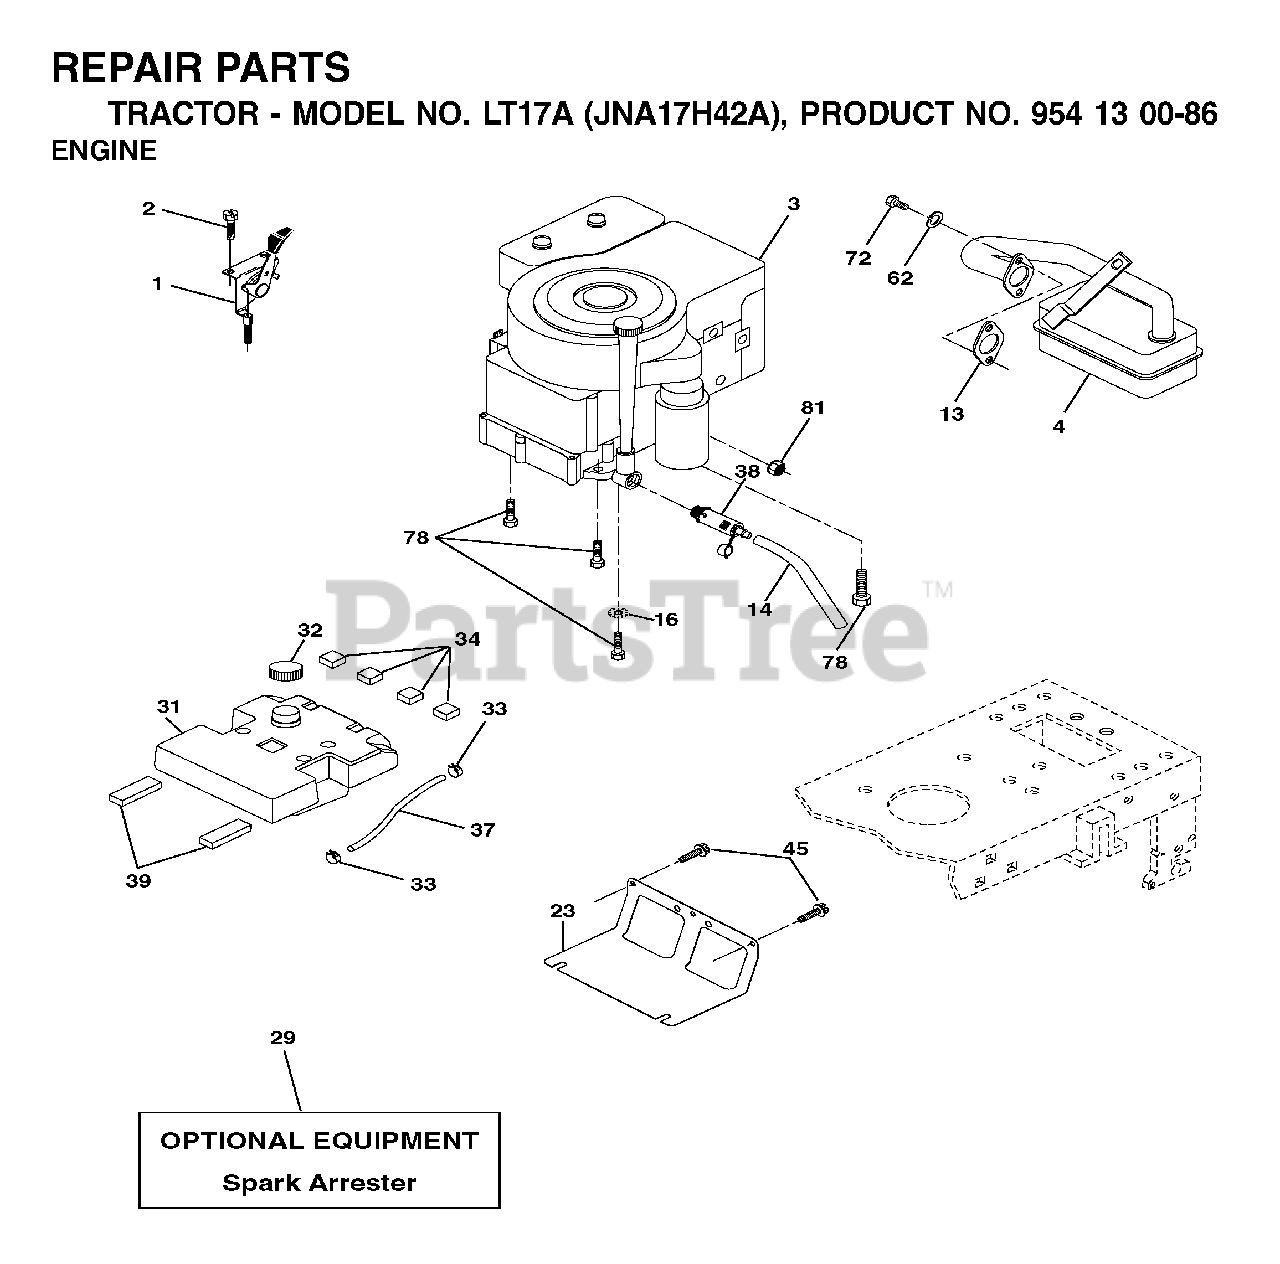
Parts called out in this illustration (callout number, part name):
1	CONTROL TH/CH FLAG
2	SCREW
13	REPL BY 532 27 22-93
14	TUBE, DRAIN OIL ASM.
16	LOCKWASHER
23	SHEILD.BROWNING.DBR.GUARD
29	ARRESTER SPARK (OPTIONAL)
31	TANK.FUEL(3.5.GAL)
32	FUEL CAP
33	HOSE CLAMP
34	PAD-SPACER LT
38	PLUG, OIL DRAIN EASY
39	PAD IDLER TI
45	SCREW, 3/8-16X3/4
62	LOCKWASHER
72	SCREW
78	SCREW.3/8-16
81	NUT
101	FLANGE NUT
105	SCREW 3/8-16X1
